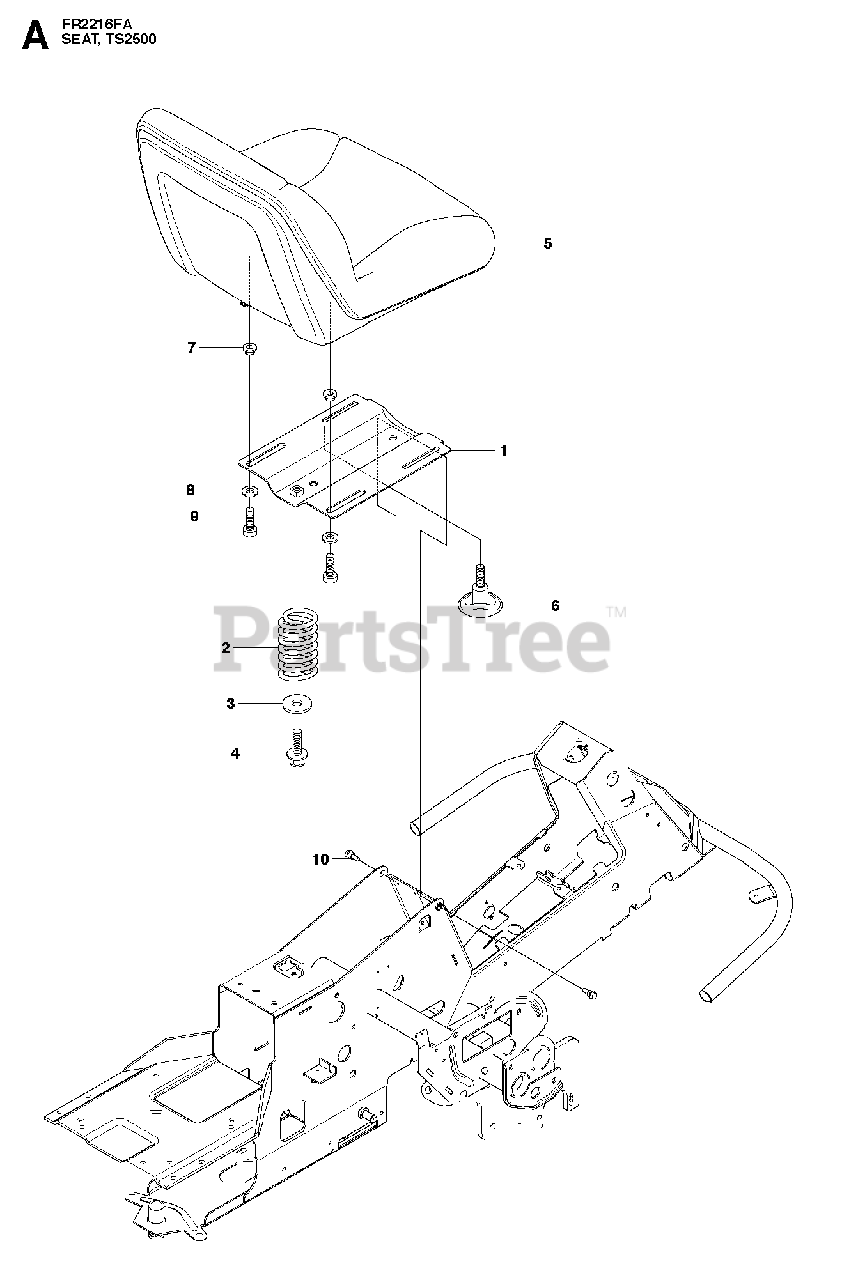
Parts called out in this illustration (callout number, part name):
2	SEAT SPRING
4	SCREW M10X25
6	ADJUSTING KNOB
